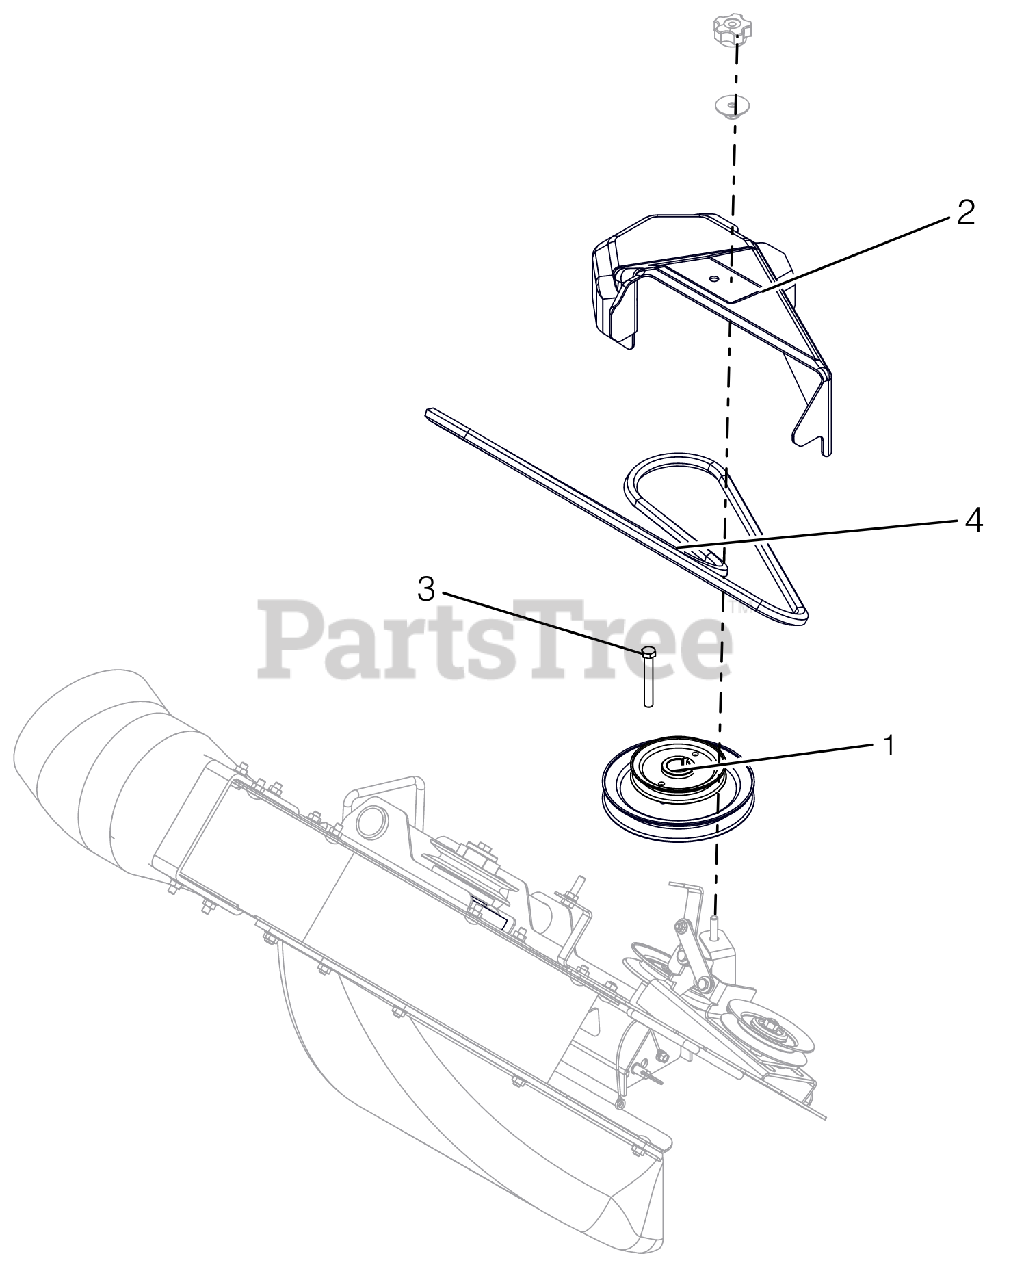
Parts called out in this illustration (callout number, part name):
1	PULLEY, DBL-1"IDX6.75"&4.25"OD
2	COVER, BELT 52 BLOWER
3	BLT-HEX .38-16X2.75 GR8 YWZC
4	HEX BELT, AA-WRAPPED
